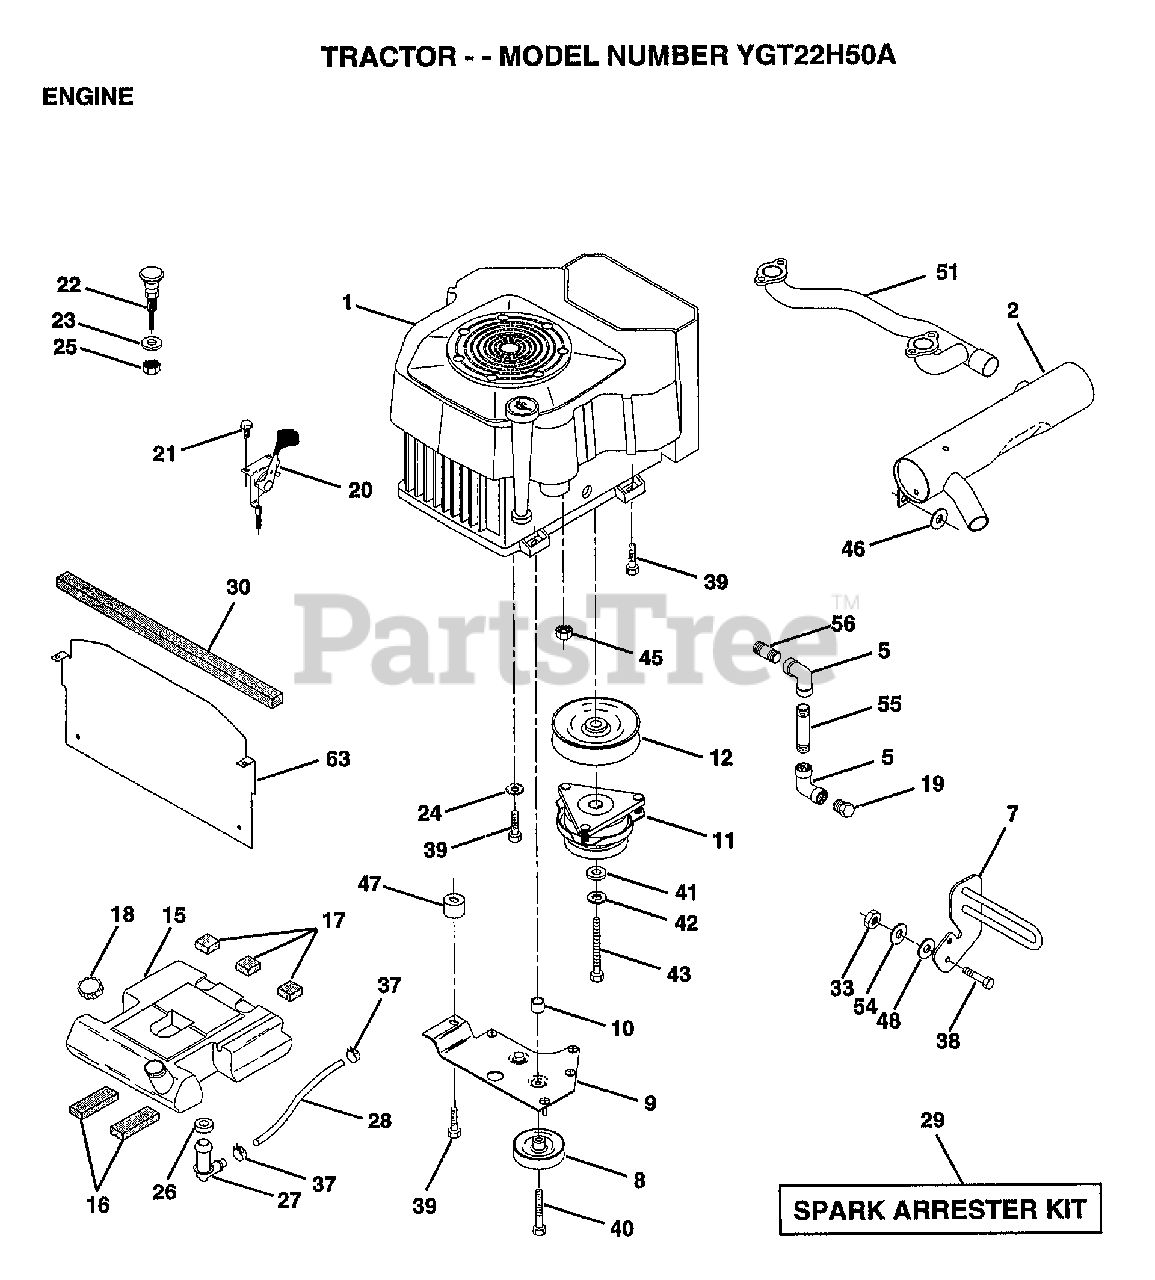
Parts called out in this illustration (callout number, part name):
1	ENGINE, KOHLER
2	MUFFLER ASM.
5	ELBOW
7	GUARD.MUFFLER.ASM
9	KEEPER ASM BELT
10	BUSHING.
12	PULLEY.ENG.CLUTCH
15	TANK FUEL REAR
16	PAD IDLER TI
17	PAD-SPACER LT
18	CAP ASM FUEL
19	PLUG T
21	SCREW LT
22	CHOKE CONTROL
23	WASHER
24	LOCKWASHER
25	"NUT,KEPS 3/8-24IM"
26	BUSHING OUTLET T
27	STEM.TANK.FUEL
29	SPARK ARREST KIT
30	FOAM-STRIP LT
33	NUT
37	HOSE CLAMP
38	"BOLT,HEX"
39	SCREW.3/8-16X2.25
40	SCREW.TT.3/8-16X4
41	WASHER
42	LOCKWASHER
43	BOLT.7/16-20X4.25
45	NUT
46	WASHER HYT
47	SPACER.ENGINE
48	WASHER T
51	PIPE CROSSOVER
54	WASHER
56	NIPPLE.PIPE
63	HEAT.SHIELD.VGT.
